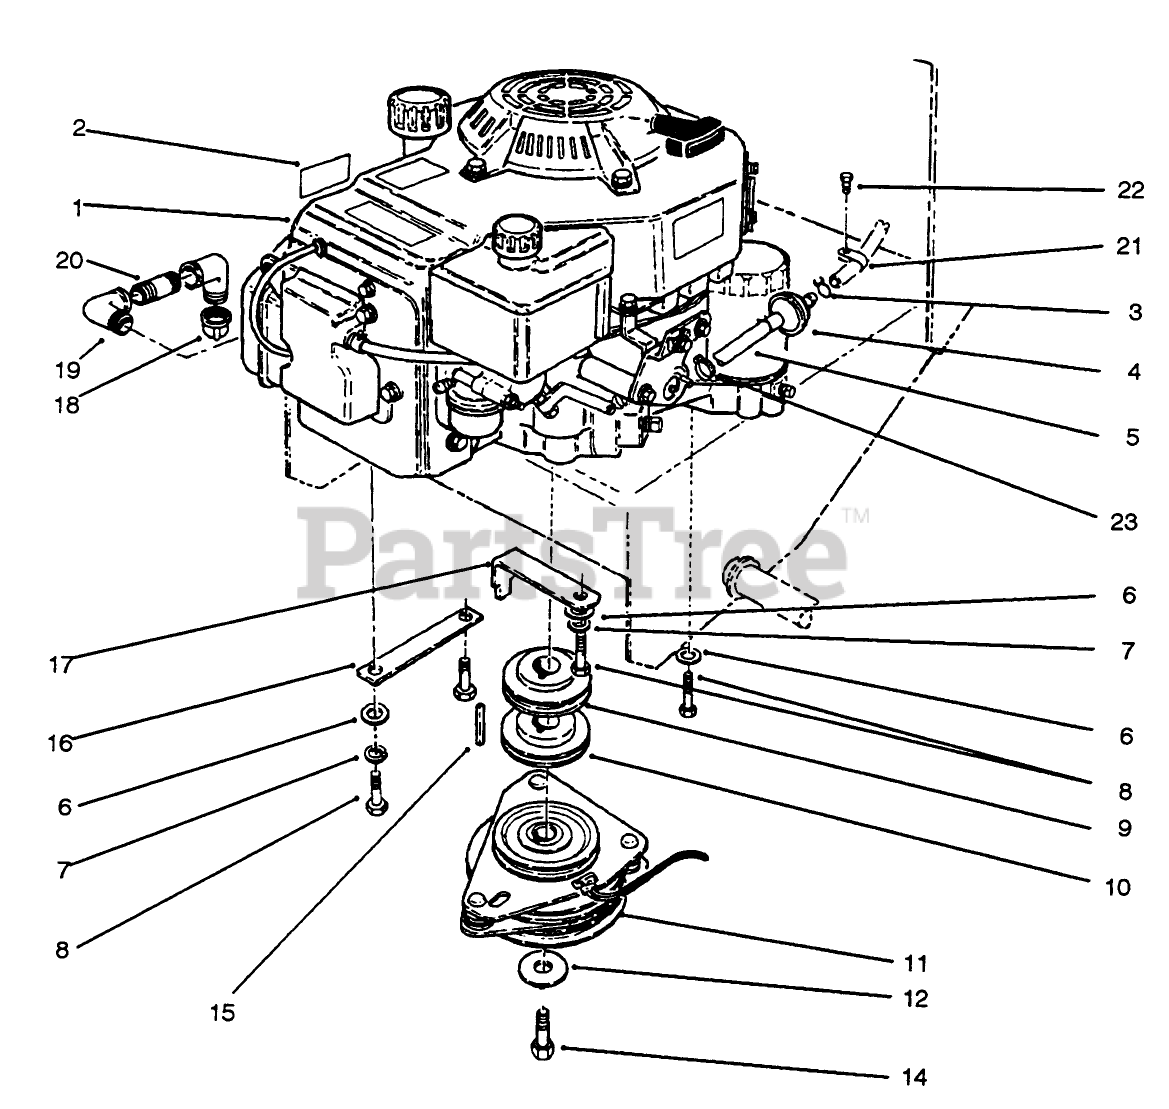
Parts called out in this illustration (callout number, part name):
2	DECAL-SURFACE, HOT
3	CLAMP-HOSE
4	FILTER-FUEL
5	HOSE-FUEL
6	WASHER-PLAIN
7	WASHER-LOCK
8	SCREW-HH
9	SHEAVE-UPPER HALF
10	SHEAVE-LOWER HALF
11	CLUTCH/BRAKE
12	WASHER
14	SCREW-CLUTCH
15	KEY-SQUARE
16	Guard-Pulley
17	Retainer-Clutch
18	CAP-PIPE
19	ELBOW-STREET, 90 DEG
20	NIPPLE
21	CLAMP-CABLE
22	SCREW-SHWH
23	CLAMP-WORM
